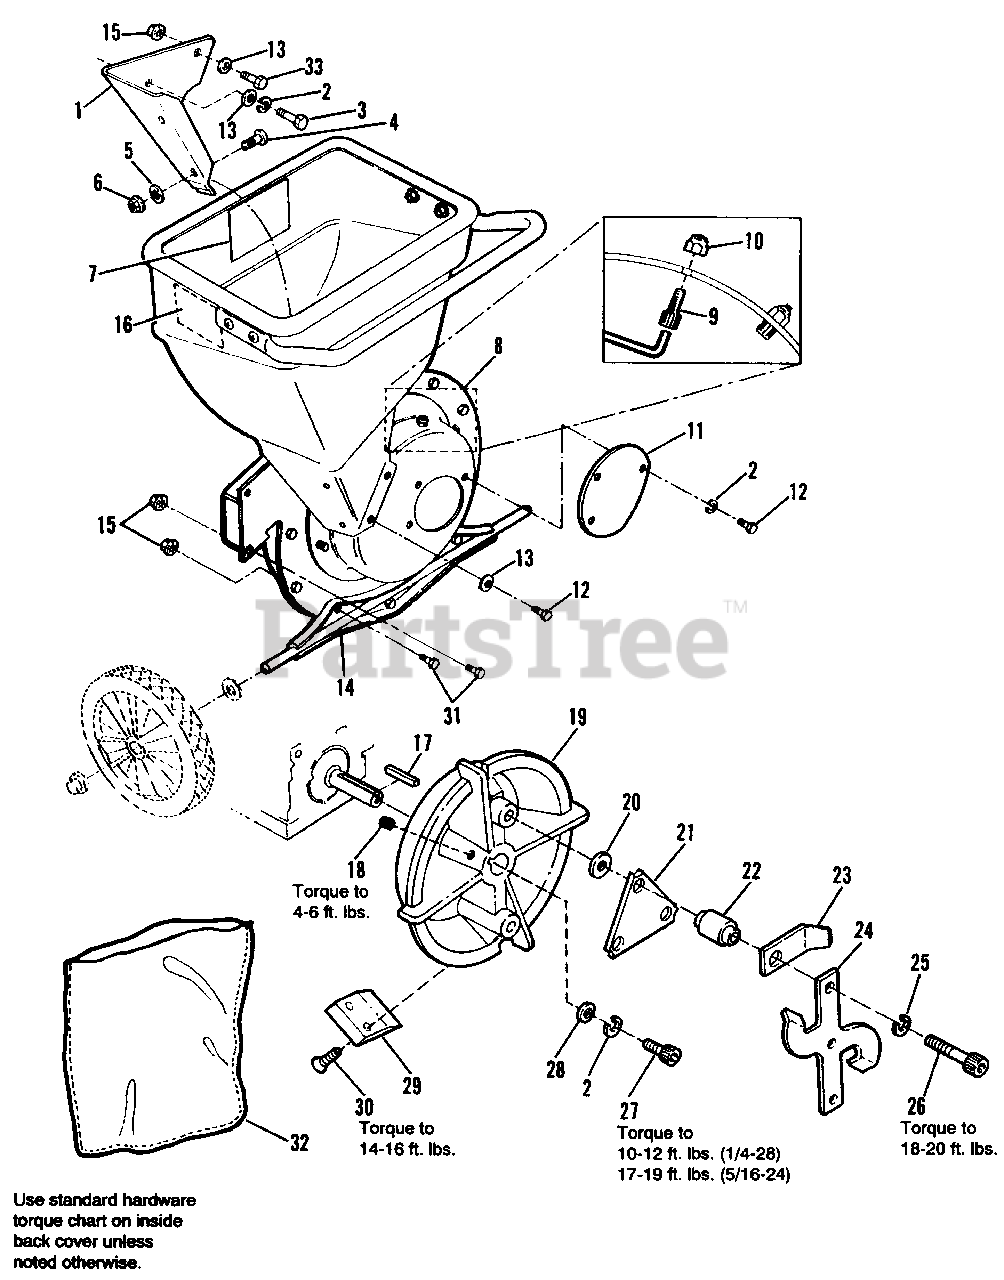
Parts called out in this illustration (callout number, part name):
1	HOPPER LINER
2	LOCKWASHER, 5/16 (Qty. 4 on Model 3C)
3	CAPSCREW, Hex Hd., 5/16-18 x 1, Gr. 5
4	SCREW, Hex, Button Hd., 1/4-20 x 3/4
5	WASHER, Flat, 1/4
6	NUT, 2-Way, 1/4-20
7	DECAL, Caution/Operate
8	BAFFLE PLATE ASSY.
9	CAPSCREW, Socket Hd., 5/16-18 x 1/2
10	NUT, Nylock, 5/16-18
11	COVER, Rotor Housing
12	CAPSCREW, Hex Hd., 5/16-18 x 1/2
13	WASHER, Flat, 5/16
14	A x LE ASSY.
15	NUT, Whiz Lock, 5/16-18
16	DECAL, Danger
17	KEY, 3/16 x 1/4 x 1-7/8
18	SETSCREW, 1/4-20 x 3/8
20	WASHER, 3/8
21	HAMMER, Triangular
24	BOOSTER FAN
25	LOCKWASHER, 3/8
26	CAPSCREW, Hex. Socket Hd., w/Patch, 3/8-16 x 2 1/2
27	CAPSCREW, Hex. Socket Hd., w/Patch, 5/16-24 x 1 (2C Only)
27	CAPSCREW, Hex. Socket Hd., w/Patch, 1/4-28 x 1 (3C Only)
28	WASHER, 5/16 (2C Only)
28	WASHER, 1/4 (3C Only)
30	SCREW, Machine, Socket Flat. Hd., 5/1 5/16-18 x 3/4
31	CAPSCREW, Hex Hd., 5/16-18 x 5/8
32	BAG, 24" x 36"
33	CAPSCREW, Hex Hd., 5/16-18 x 3/4, Gr.5
